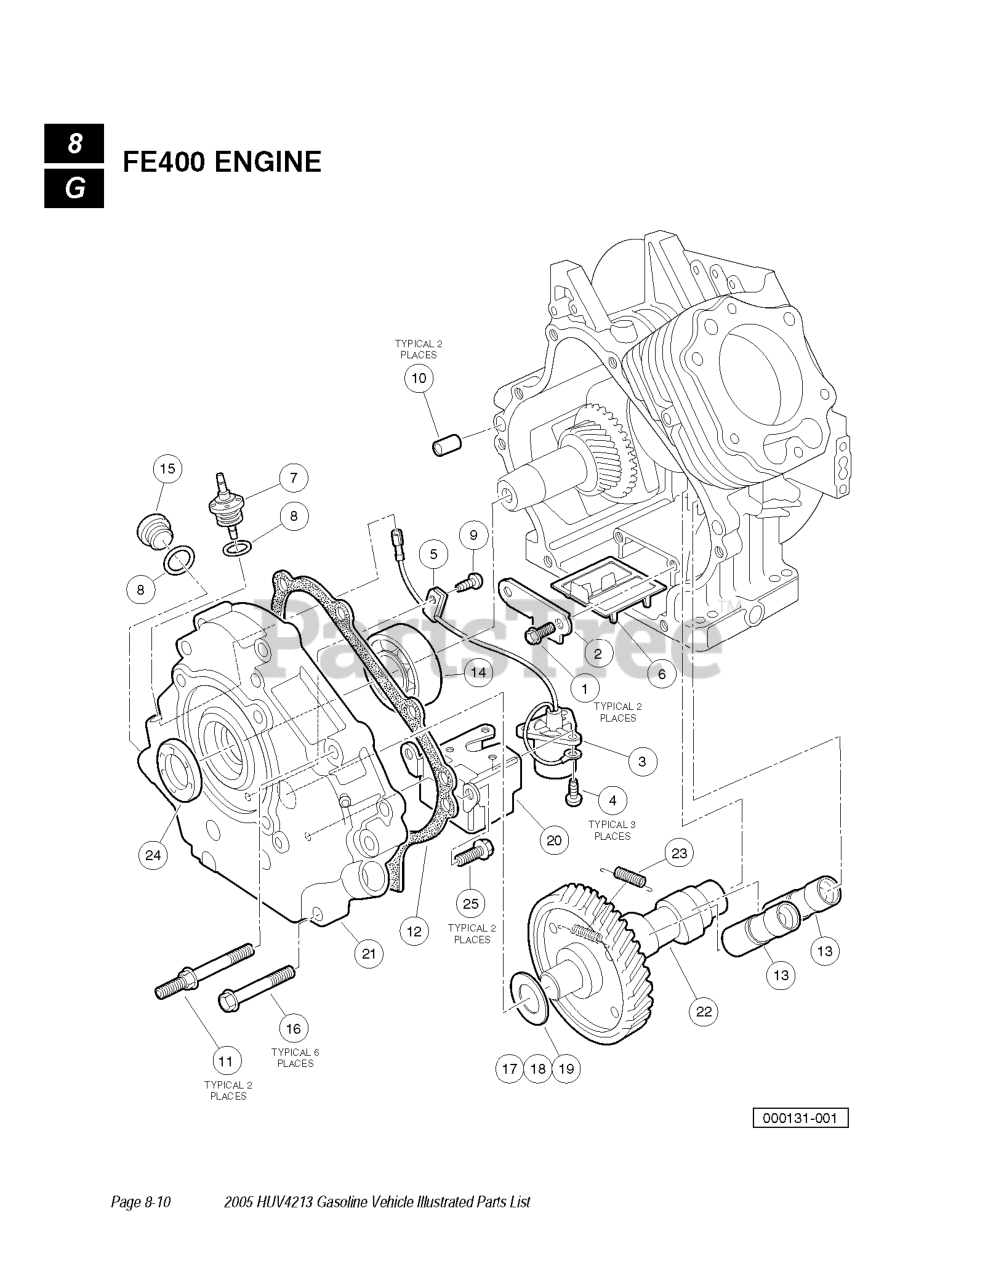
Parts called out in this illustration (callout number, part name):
1	BOLT, FLANGED
2	OIL FILTER SCREEN PLATE
3	SENSOR, FE290 OIL LEVEL
4	SCREW, PAN, CROSS
6	OIL FILTER SCREEN
7	CONNECTOR - CORD
12	GASKET - CRANKCASE COVER
13	ADJUSTER, LASH
14	BEARING, BALL
16	SCREW, M8-1.25 X 45MM HEX
17	SHIM - T=0.3
18	SHIM - T=0.4
19	SHIM - T=0.5
20	SWITCH BRACKET
21	FE400 CRANKCASE COVER
22	CAMSHAFT, FE350/400 W. ACR 44T
24	FE400 OIL SEAL
25	BOLT SWITCH BRACKET
26	GASKET KIT, FE400
